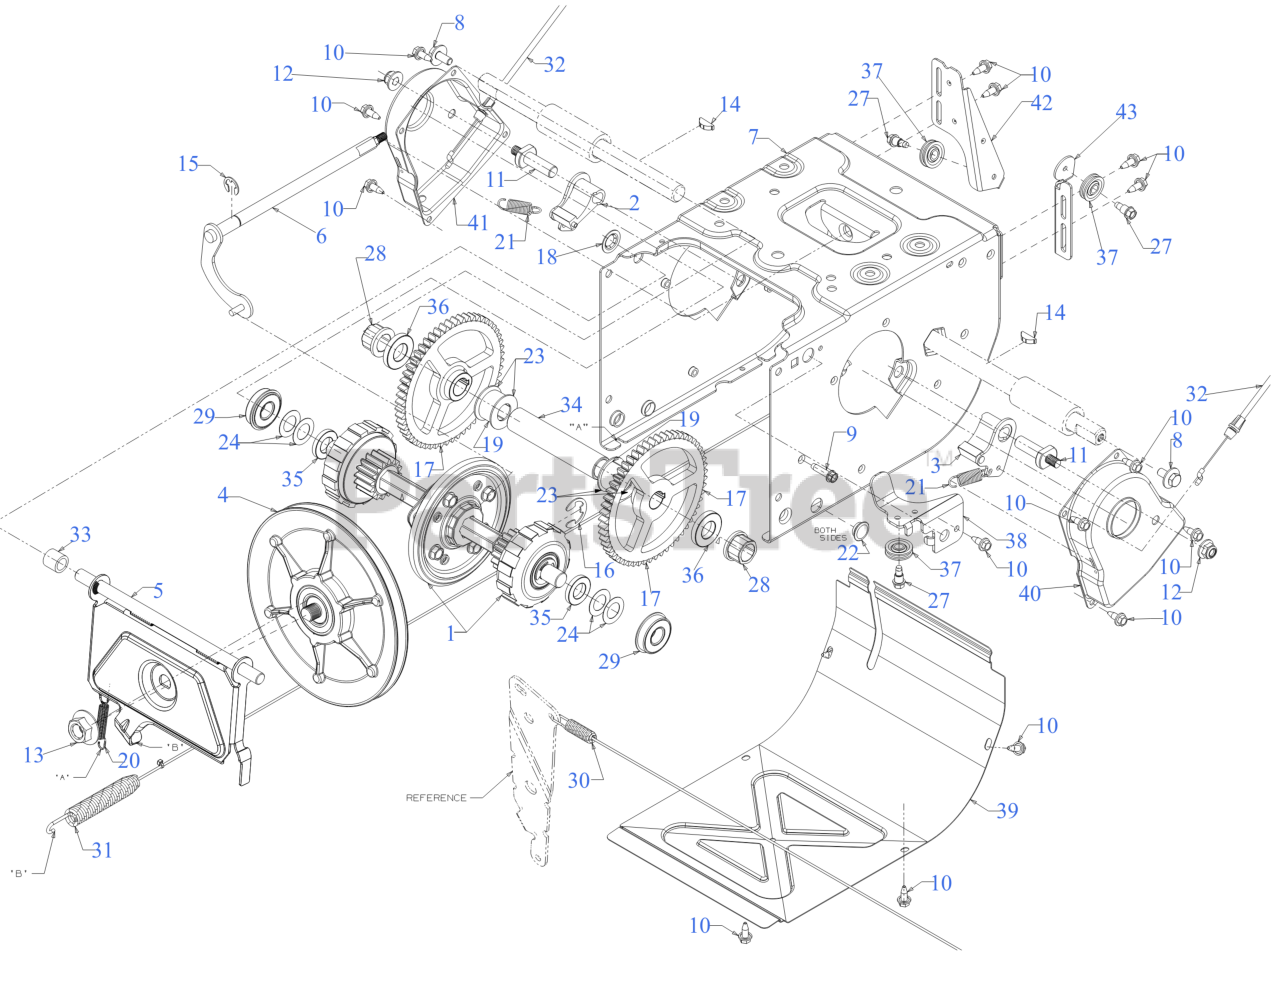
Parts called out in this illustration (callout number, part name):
1	PLANETARY FRICTION WHEEL HEX SHAFT
1	CARRIER ASSEMBLY
1	FRICTION WHEEL ASSEMBLY
2	DOGG ASSEMBLY (RH)
3	DOGG ASSEMBLY (LH)
4	FRICTION WHEEL DISC ASSEMBLY
5	FRICTION WHEEL BRACKET (POWDER BLACK)
6	SHIFT ROD ASSEMBLY
7	DRIVE FRAME
8	SCREW 5/16-24 x .750 GR5
9	SCREW 1/4-20 x 1.00
10	SCREW 1/4-20X.625
11	ACTUATOR SHAFT
13	FLANGE NUT 5/8-18
14	KEY 3/16 x 3/4
15	E-RING FOR .500 SHAFT
16	RETAINING RING
19	SPACER: .76ID x .75
20	EXTENSION SPRING
21	EXTENSION SPRING
23	FLAT WASHER .760ID X1.49OD x .06
23	FLAT WASHER
24	FLAT WASHER .67X 1.174X .02
27	SHOULDER SCREW
28	FLANGE BEARING
29	BALL BEARING W/RET
30	AUGER DRIVE CABLE 47.48"
31	WHEEL DRIVE CABLE 44.955"
32	STEERING CABLE
33	SPACER-.513 ID x .703 OD x .69
34	AXLE SUPPORT TUBE
36	AXLE SPACER
37	CABLE GUIDE ROLLER
38	AUGER CABLE BRACKET
42	CABLE GUIDE BRACKET (DRIVE)
43	CABLE GUIDE BRACKET (AUGER)
